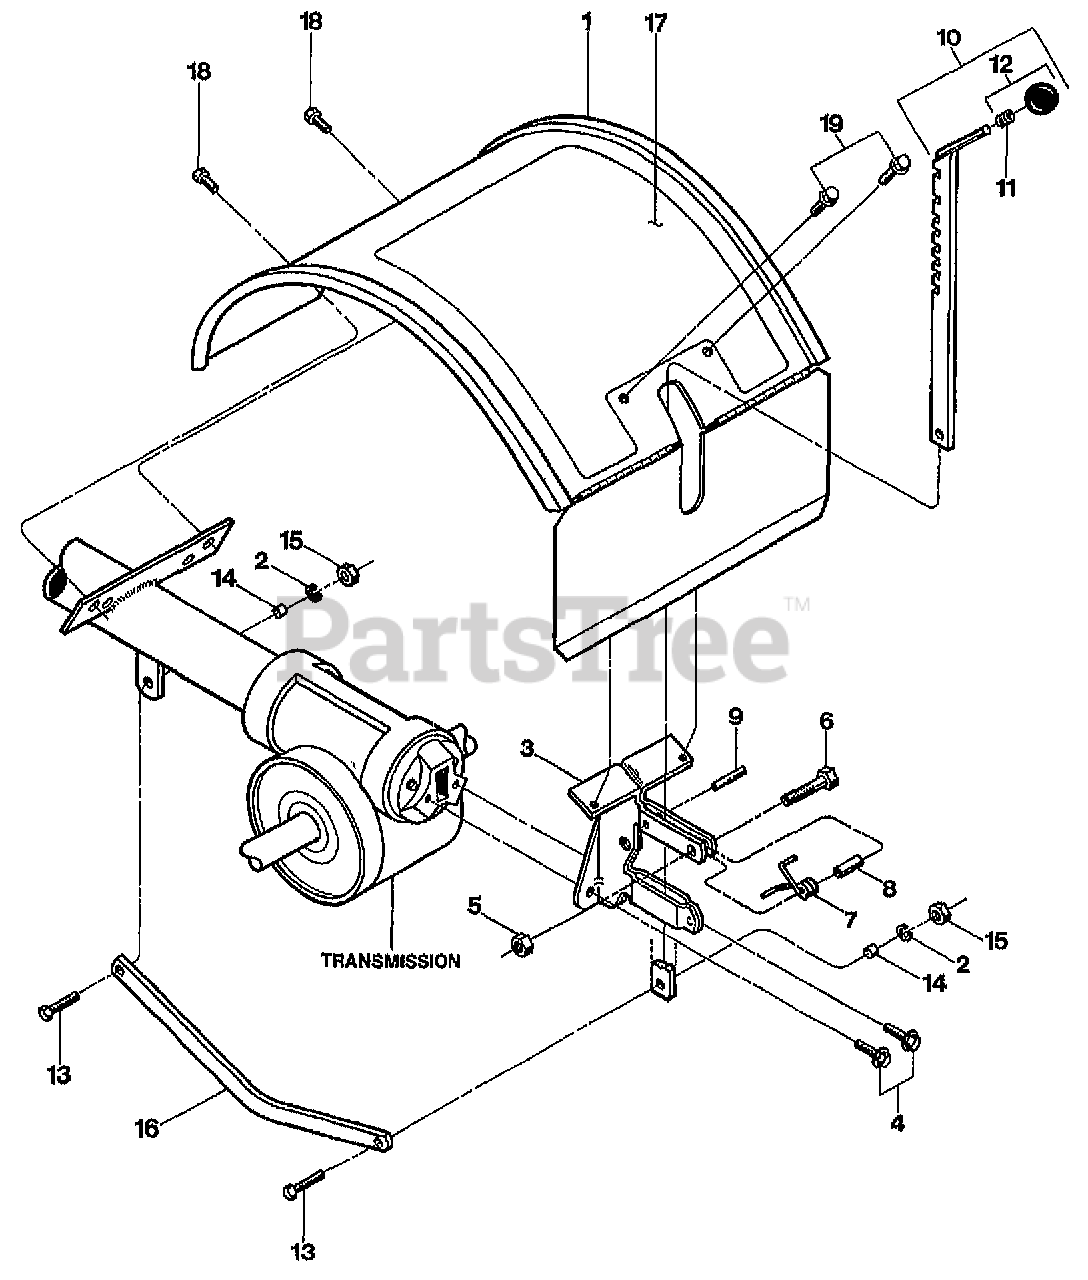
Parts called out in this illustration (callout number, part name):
1	HOOD W/DECALS JR 0PC (INCL. 17)
1	HOOD W/DECALS JUNIOR (INCL. 17)
2	WASHER-LK .375 @ DEPL
3	BRKT W/ROLL PIN (9308) (INCL.9)
4	SCR-HFLK 5/16-18X.62 G5ZP
5	NUT-LK 1/4-20
6	SCR-HH 1/4-20X1.0
7	SPRING-TORSION
8	SPACER-.250X.343X.375
9	PIN-ROLL .25 X 1
10	DEPTH REGULATOR W/KNOB (INCL. 11-12)
11	RING-TOLERANCE .5325 ID
12	KNOB-CONTROL (INCL.11)
13	SCR-HH 3/8-16X1.25
14	BUSHING-.5X.375X.3
15	NUT-HEX 3/8-16 ZP
16	DRAG BAR-BENT (DEPTH REGULATOR)
17	DECAL-HOOD JR
17	DECAL-HOOD INST JUNIOR
18	SCR-HWH 5/16-18 X .5 STH
19	SCR-HWH 1/4-20 X .5 STH
